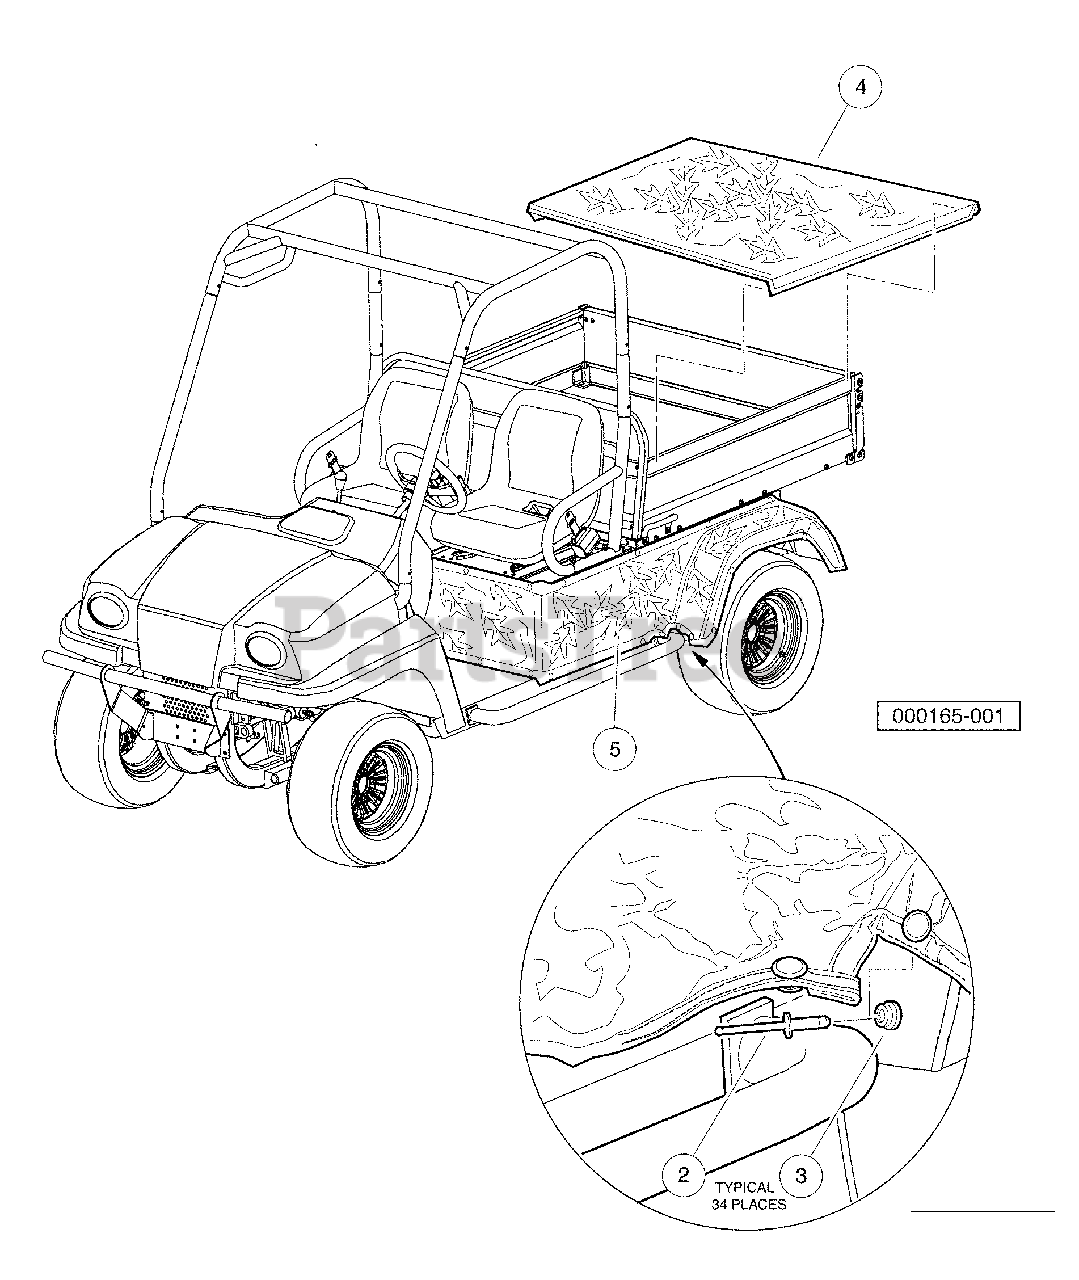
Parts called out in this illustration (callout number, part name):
1	Kit, Camouflage Cover
2	Rivet, 0.125" Dia
4	Cover, Camouflage Cargo Box
5	Wrap, Camouflage Rear Body
